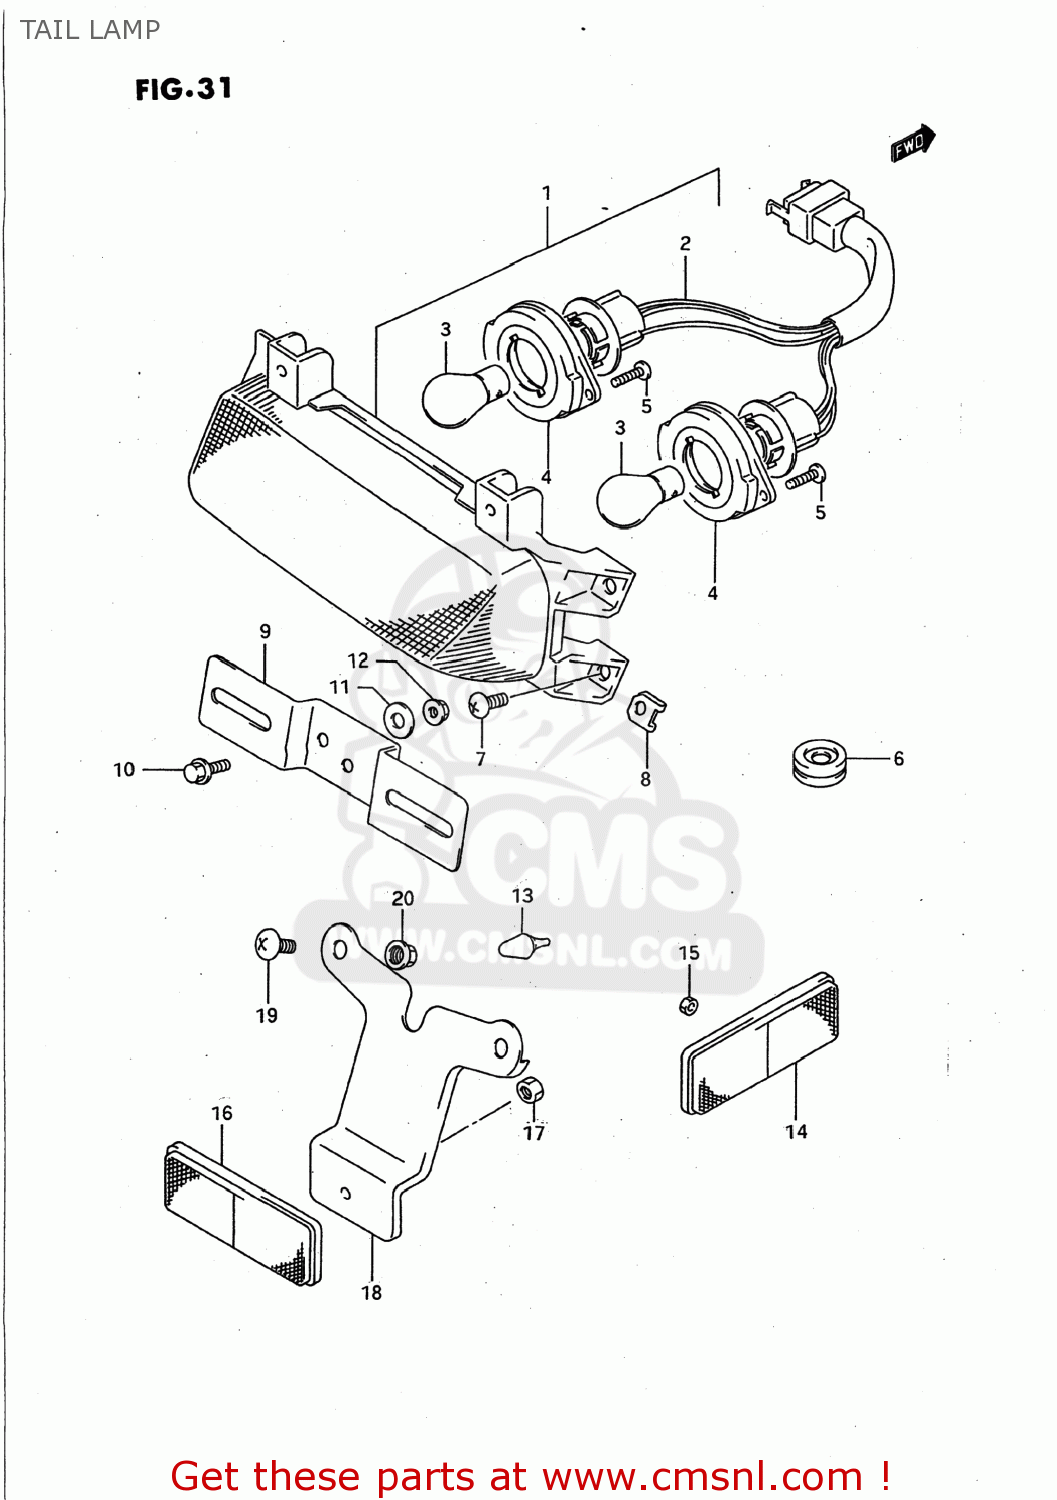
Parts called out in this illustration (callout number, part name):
1	LAMP ASSY,RR COMBINATION
2	SOCKET & CORD ASSY
3	BULB(12V21/5W,BF141-49642A)
4	CUSHION
5	SCREW
6	GROMMET
7	SCREW 5X12
8	NUT
9	BRACKET,LICENSE PLATE
10	BOLT
11	WASHER,COVER,FRONT
12	NUT
13	CUSHION
14	REFLECTOR ASSEMBLY,REAR
15	NUT
16	REFLECTOR ASSY,RR
17	NUT
18	BRACKET,RR RR
19	SCREW 6X12
20	NUT
